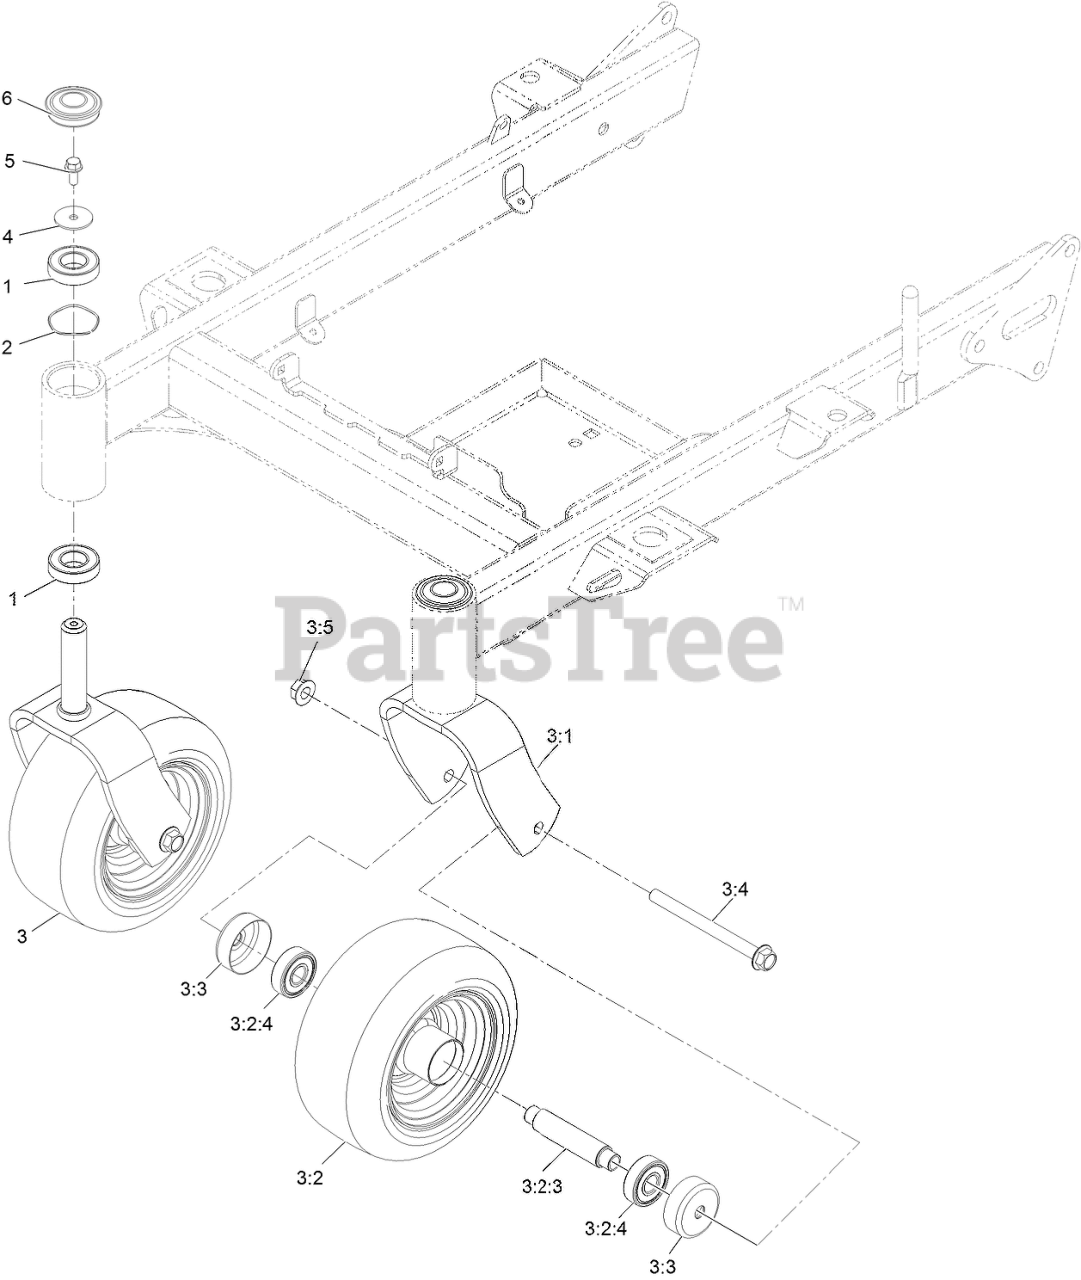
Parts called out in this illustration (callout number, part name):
1	BEARING-BALL
3	ASM-Caster Fork W/Tire
3:1	ASM-Caster Fork [red]
3:2	ASM-Tire&whl Sp 9X4.50-5
3:2:3	AXLE-CASTER
3:2:4	BEARING
3:3	Guard-Seal
3:4	SCREW-HHF
4	WASHER-FLAT
5	SCREW-HHF
6	CAP-GREASE
